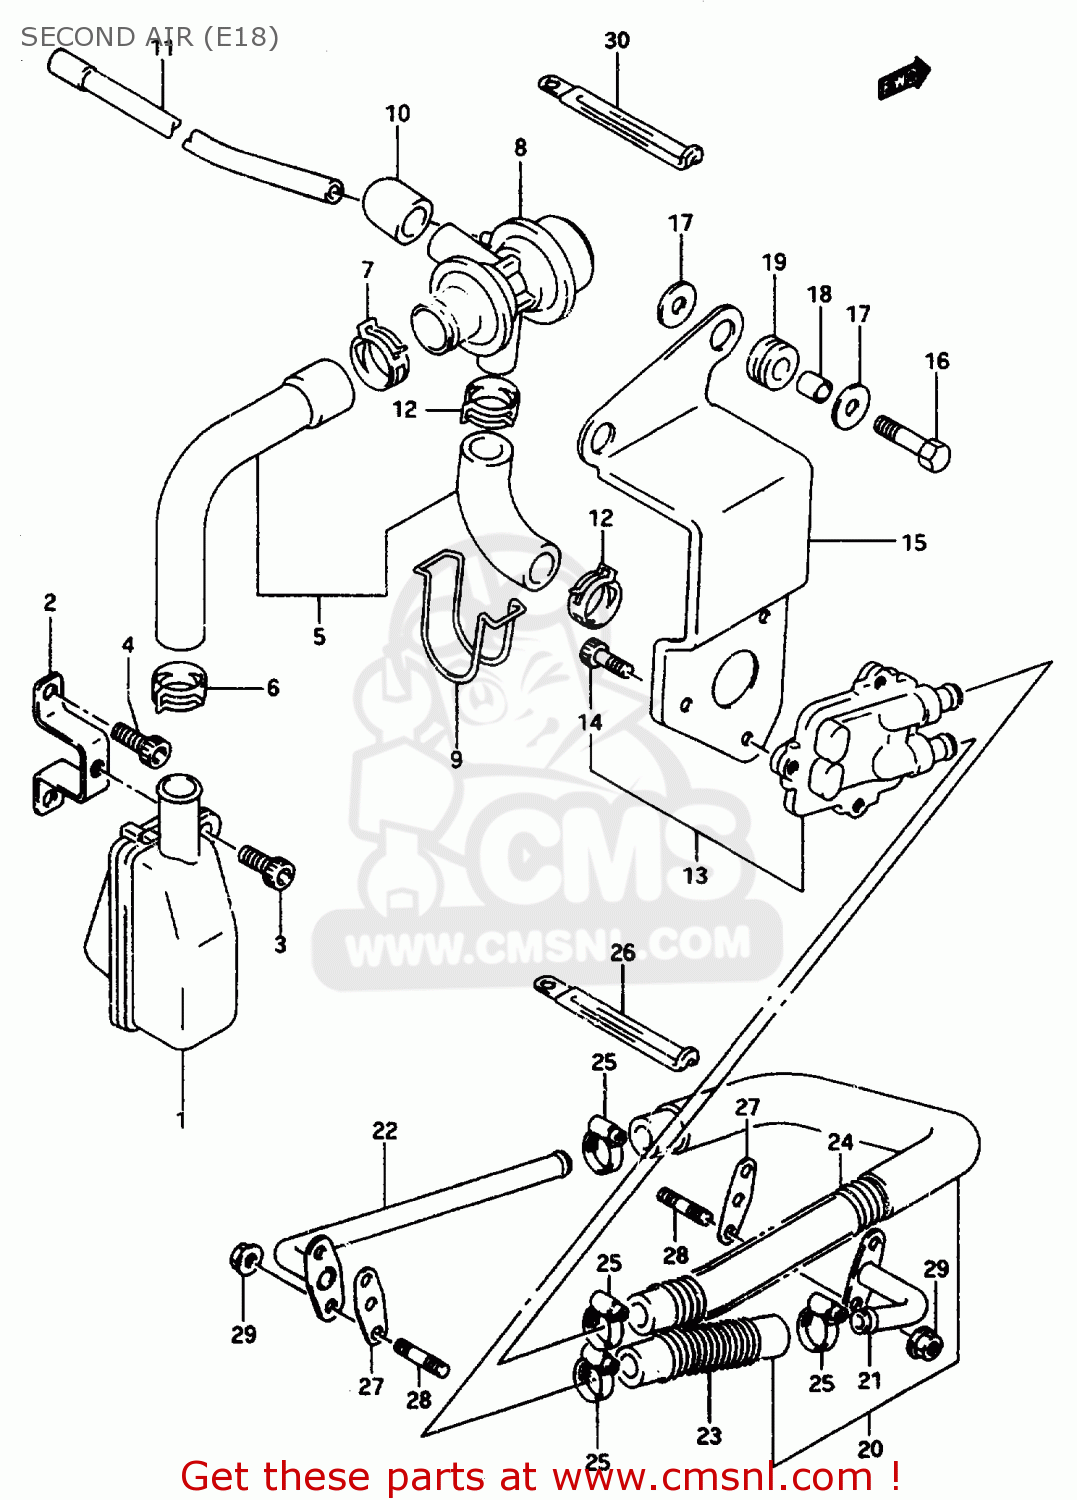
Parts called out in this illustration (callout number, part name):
1	CLEANER ASSY,AIR NO.2
2	BRACKET,2ND AIR CLEANER
3	BOLT
4	BOLT
5	HOSE SET,2ND AIR NO.2
6	CLIP
7	CLIP
8	VALVE ASSY,AIR SWITCHING
9	CLAMP,SWITCHING VALVE
10	CAP,SWITCHING VALVE
11	HOSE(4.5X8.5X600)
12	CLIP
13	VALVE ASSY,2ND AIR REED
14	BOLT
15	BRACKET, 2ND AIR VALVE
16	BOLT
17	WASHER(6.5X20X1.6)
18	SPACER(6.5X10X10)
19	CUSHION
20	HOSE SET, 2ND AIR
21	PIPE,2ND AIR FR
22	PIPE,2ND AIR RR
23	SPRING, FRONT HOSE
24	SPRING, REAR HOSE
25	CLAMP
26	CLAMP(L:80)
27	GASKET,SECOND AIR PIPE (N (NAS)
28	STUD 6X16
29	NUT
30	CLAMP(L:80)
